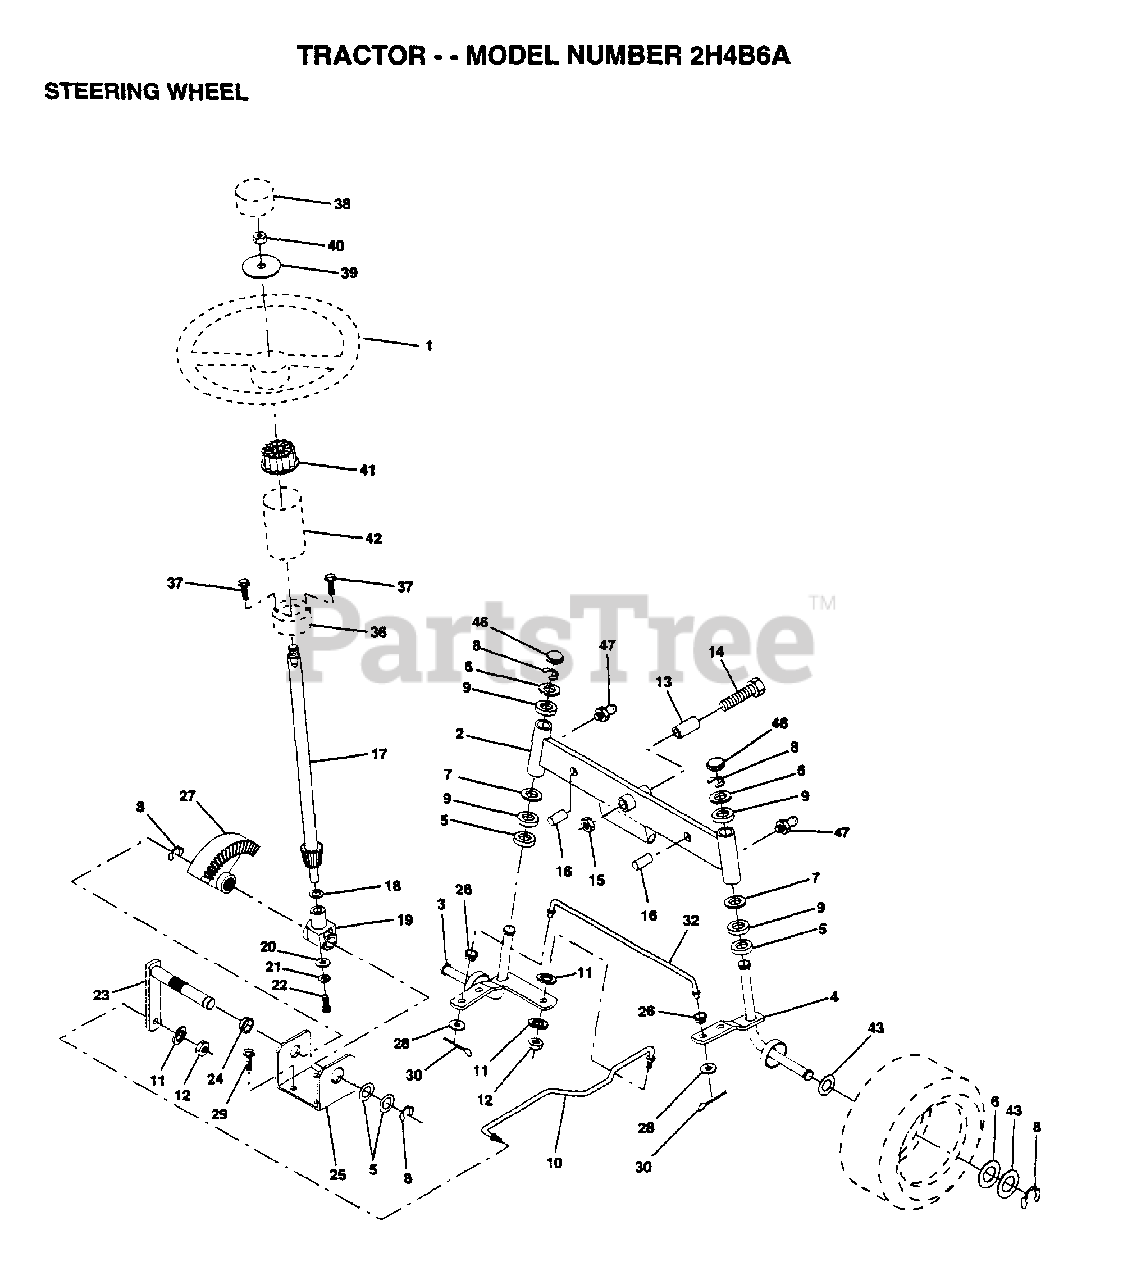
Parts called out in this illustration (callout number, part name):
2	AXLE ASM FRONT
3	SPINDLE LH
4	SPINDLE RH
5	WASHER .T
6	WASHER
7	WASHER
8	RING
9	COL. SRTG. BEAR.
11	LOCKWASHER
13	BEARING
14	BOLT HEX 5/8-11
15	"NUT-LOC,FLANGE LT"
16	AXLE PIN
17	SHAFT ASM
18	THRUST WASHER
19	SUPPORT.SHAFT
21	LOCKWASHER
22	"SCREW,SPECIAL"
24	NYLINER T
25	"BRKT,STEERING"
26	BUSHING.DRAGLINK
27	GEAR SECTOR
28	WASHER
29	SCREW
30	COTTER PIN
32	TIE ROD
38	ST WHL INSERT CAP
39	WASHER T
40	GRIPCO NUT
41	ADAPTER-WHEEL LT
42	"TUBE, STR SHAFT"
43	WASHER
46	CAP
47	ZERK M
